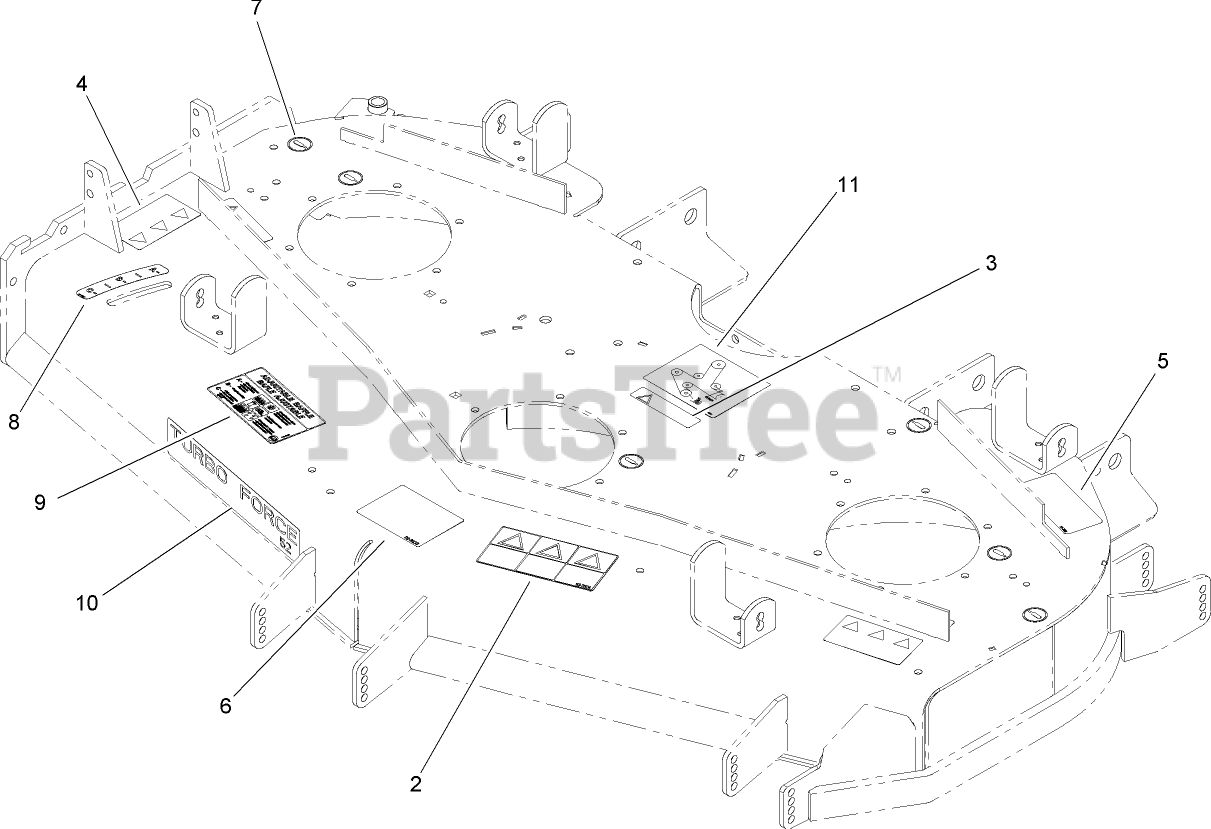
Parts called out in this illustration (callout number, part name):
2	DECAL-DANGER
3	DECAL-WARNING
4	DECAL-DANGER
5	DECAL-TORQUE, BLADE BOLT
6	DECAL-ANTI SCALP
7	DECAL-GREASE
8	DECAL-SETTING, BAFFLE
9	DECAL-ADJUSTMENT, BAFFLE
11	DECAL-ROUTING, BELT
